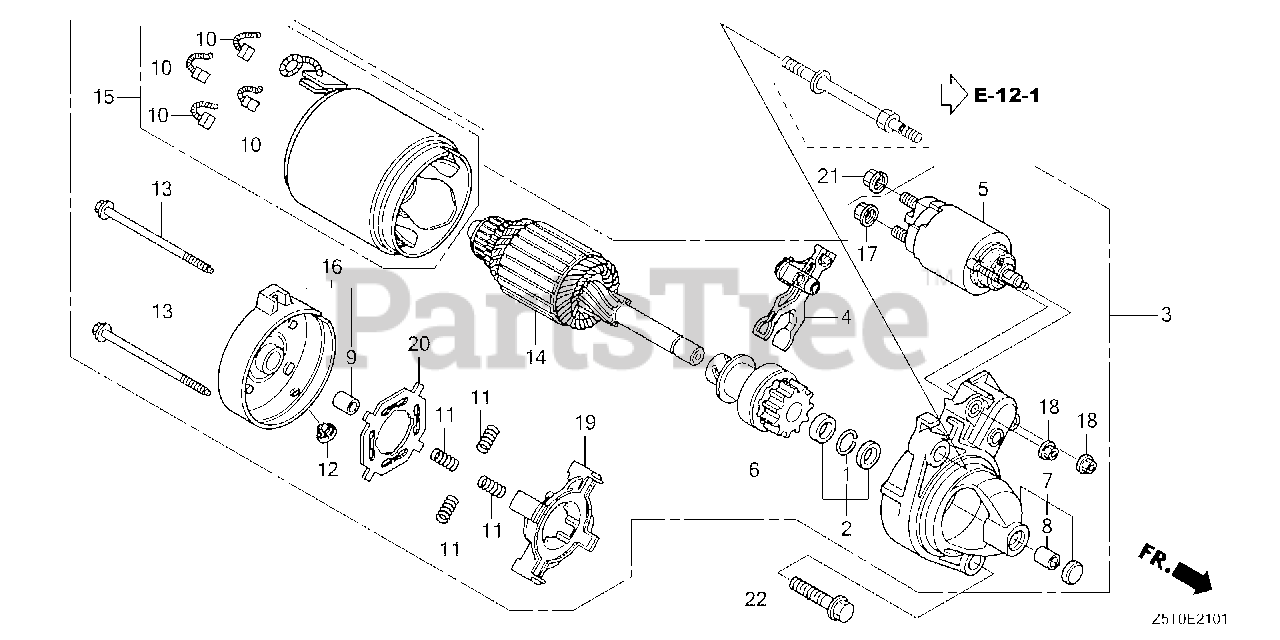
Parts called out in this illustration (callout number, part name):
1	RING, SNAP (DENSO)
2	COLLAR SET, CLUTCH STOP
3	STARTER MOTOR ASSY.
4	LEVER, PINION DRIVE
5	SWITCH ASSY., MAGNET
6	CLUTCH, OVERRUNNING
7	HOUSING, DRIVE SIDE
9	BEARING B
10	BRUSH
11	SPRING, BRUSH
13	BOLT, THROUGH
16	FRAME, COMMUTATOR END
17	NUT, HEX. (8MM)
18	NUT, FLANGE (5MM)
19	HOLDER, BRUSH
20	INSULATOR, BRUSH HOLDER
21	NUT-WASHER (8MM)
22	BOLT, FLANGE (10X40)
